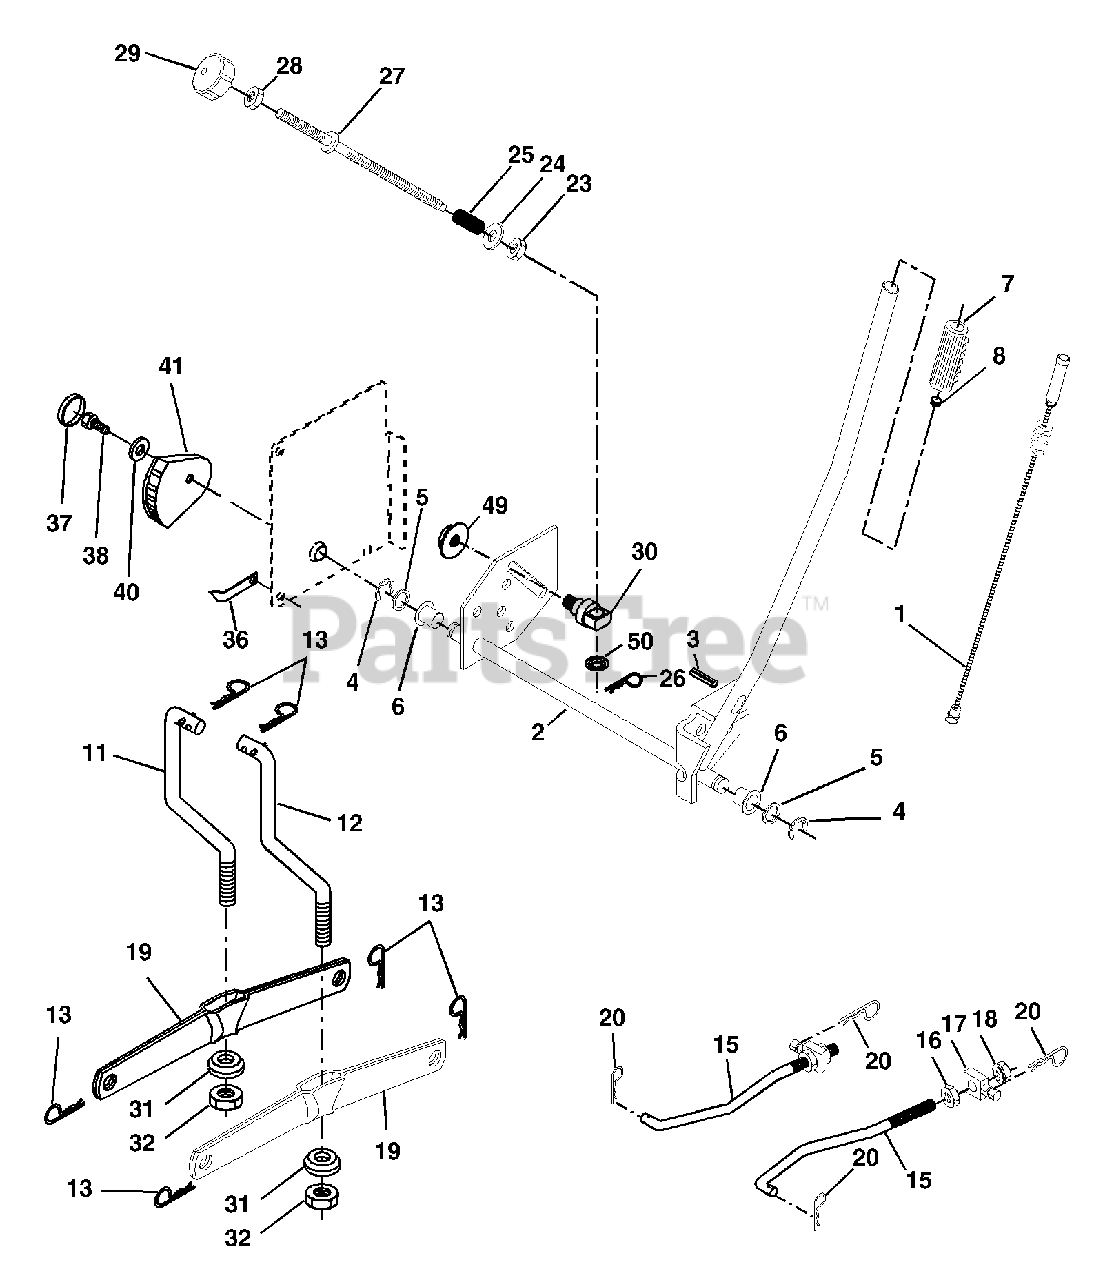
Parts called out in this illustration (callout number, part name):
1	Wire Asm Inner/Sprg W/plunger
2	Shaft Asm Lift RH w/Inf
3	Pin Groove
4	E Ring #5133-62
5	Washer 21/32 x 1 x 21 Ga.
6	Bearing Nylon Blk 629 Id
7	Grip Handle
8	Button Plunger
11	Link Lift LH Fixed Length
12	Link Lift RH Fixed Length
13	Retainer Spring
15	Link Front
16	Nut Jam Hex 1/2-13 unc
17	Trunnion
18	Nut Lock W/Wsh 1/2-13 unc
19	Arm Suspension Rear
20	Retainer Spring
23	Nut Special
24	Washer 13/32 x 5/8 x 16 Ga.
25	Spring 2-1/8"
26	Retainer Clip
27	Rod Adj Lift Zinc 7.49 Wrk Lg
28	Nut Hex Jam 3/8-16 unc
29	Knob Inf 3/8-16 unc Blk W/sym
30	Trunnion Infin Height
31	Bearing Pvt Lift
32	Nut Crownlock 3/8 - 24
36	Pointer Height Indicator
37	Plug Hole Blk 1.485/1.515 Dia.
38	Screw 5/16-18 x 1
40	Washer 11/32 x 1-1/2 10 Ga.
41	Indicator Height STLT
49	Nut Hex Flange Lock
50	Nut PUsh Phos & Oi
